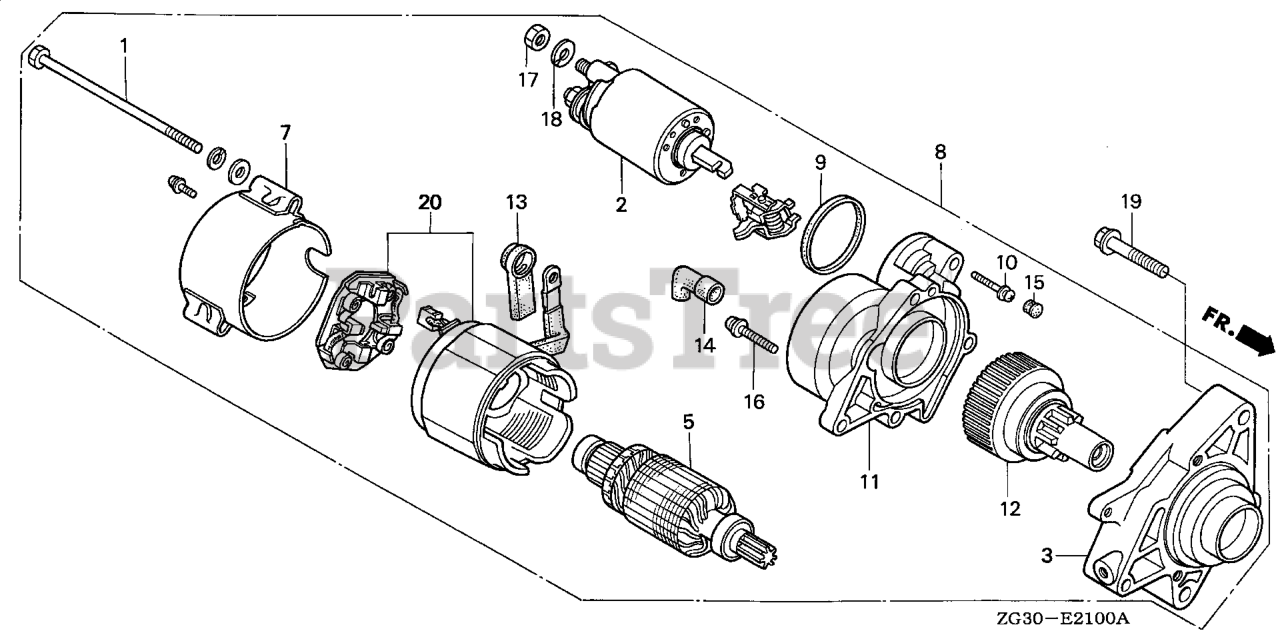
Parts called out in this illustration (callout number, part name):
1	BOLT, THROUGH
2	SWITCH ASSY., MAGNETIC
3	COVER, GEAR
5	ARMATURE (N/A: SEE ASSEMBLY)
7	BRACKET, RR.
8	STARTER MOTOR ASSY.
9	RING, SQUARE (MITSUBA) (NOT AVAILABLE)
10	SCREW-WASHER (4X28) (MITSUBA)
11	CASE, FR.
12	GEAR ASSY.
13	COVER, TERMINAL
14	TUBE, LABYRINTH
15	BUSH, RUBBER
16	SCREW-WASHER (6X30)
17	NUT,HEX 8MM
18	WASHER, SPRING (8MM)
19	BOLT, FLANGE (8X40) Use up to Engine SN 1003236.
20	STATOR SET
